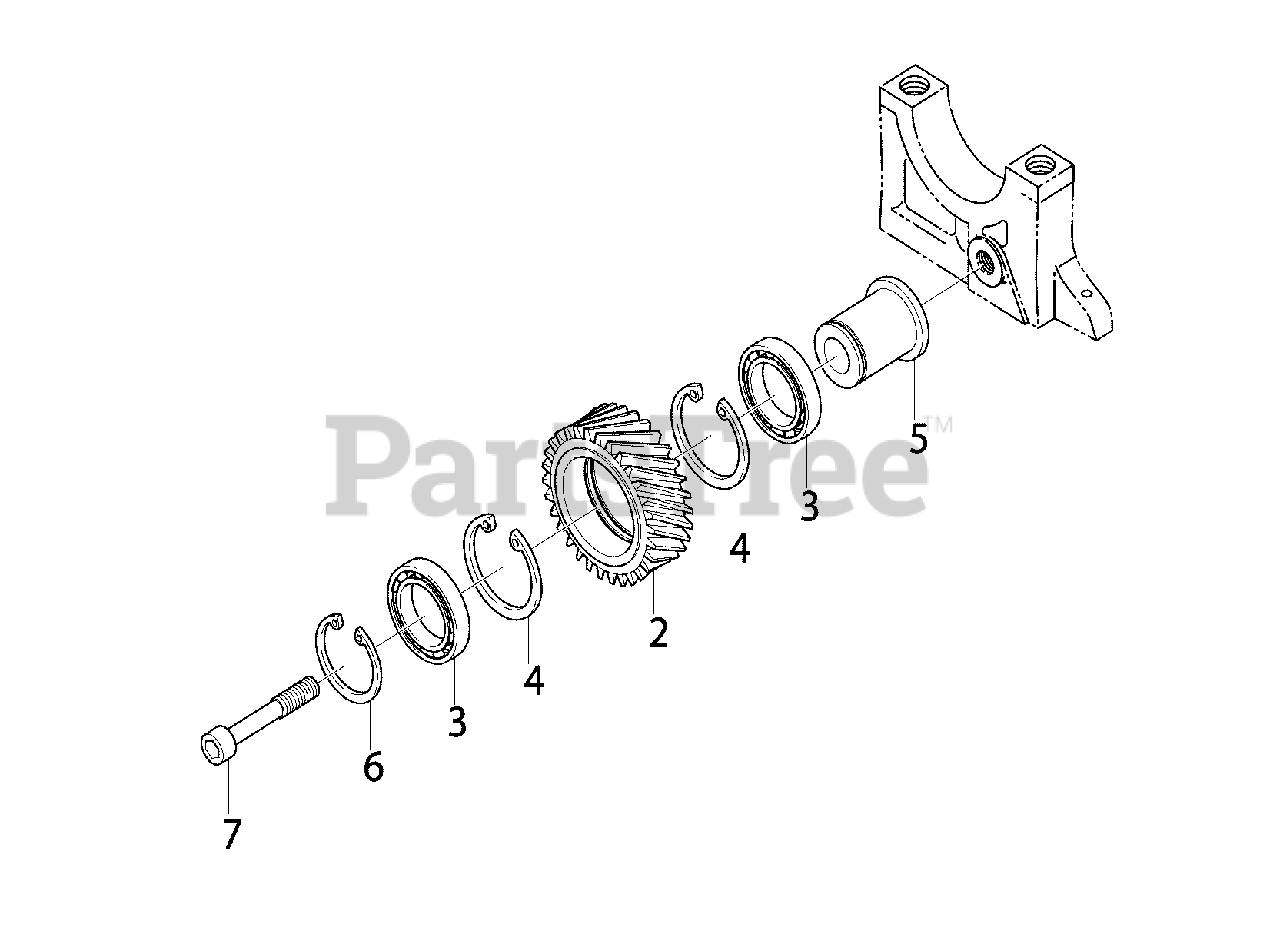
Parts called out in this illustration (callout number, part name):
2	* GEAR, IDLER
3	* BEARING, BALL
4	* RING, SNAP
5	* PIN, IDLER GEAR
6	* RING, SNAP
7	* BOLT
